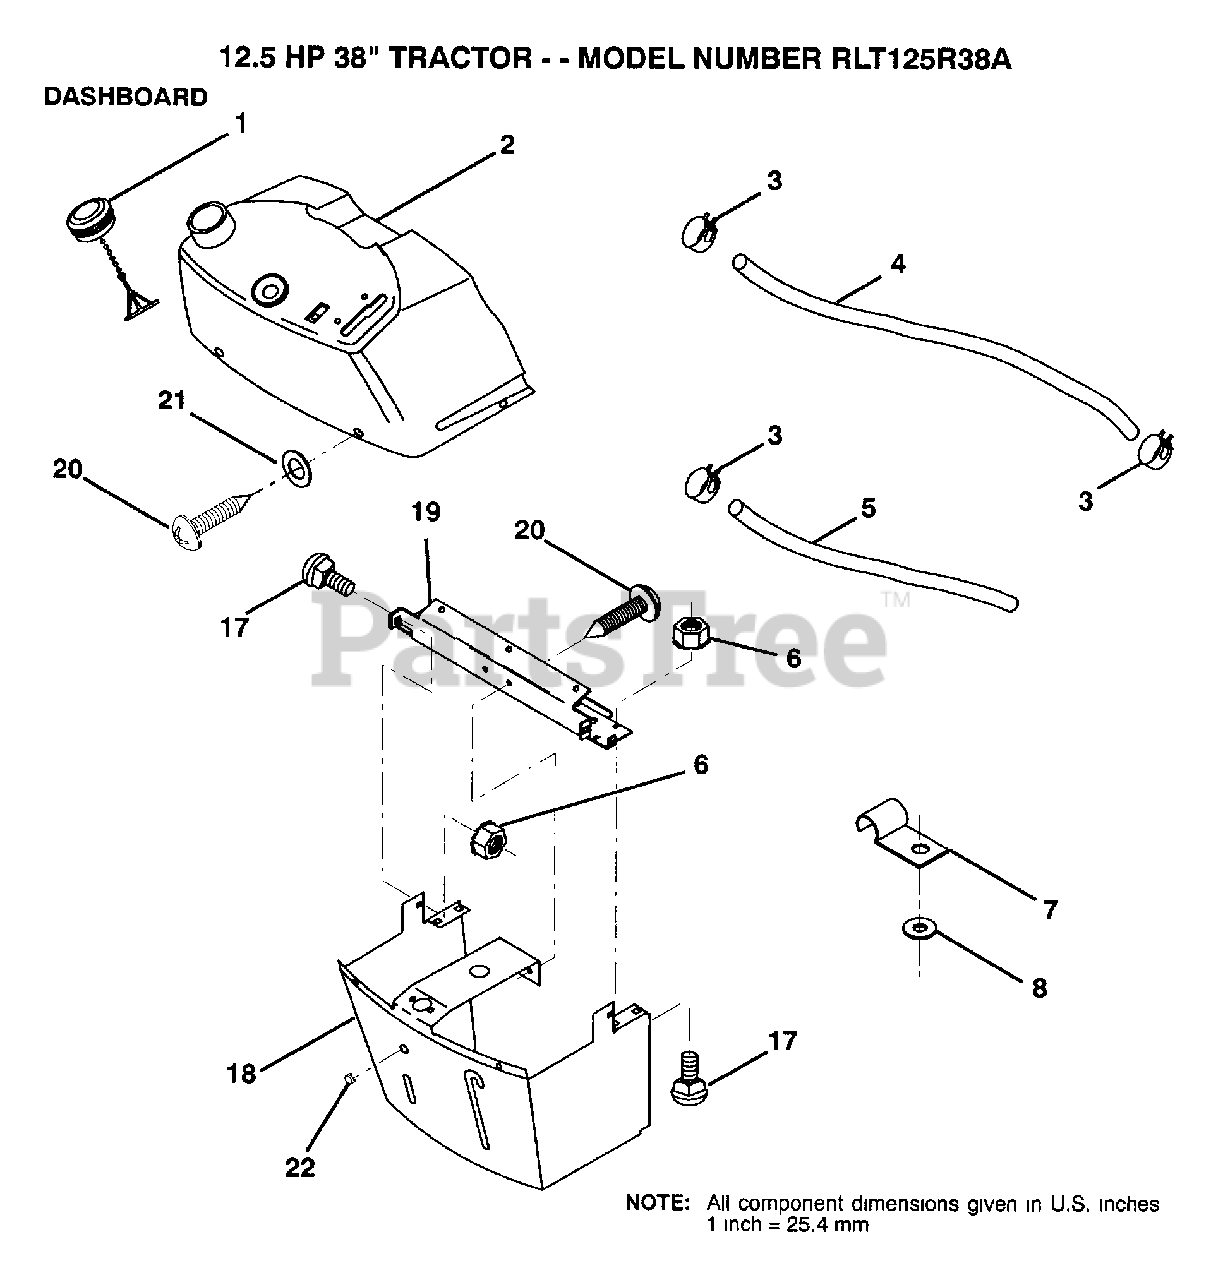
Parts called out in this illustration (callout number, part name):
3	HOSE CLAMP
5	FUEL LINE T
6	NUT
7	CLIP T
8	WASHER PM
17	BOLT
18	SUPT ASM DASH
19	CROSS BRACE
22	PLUG DOME
